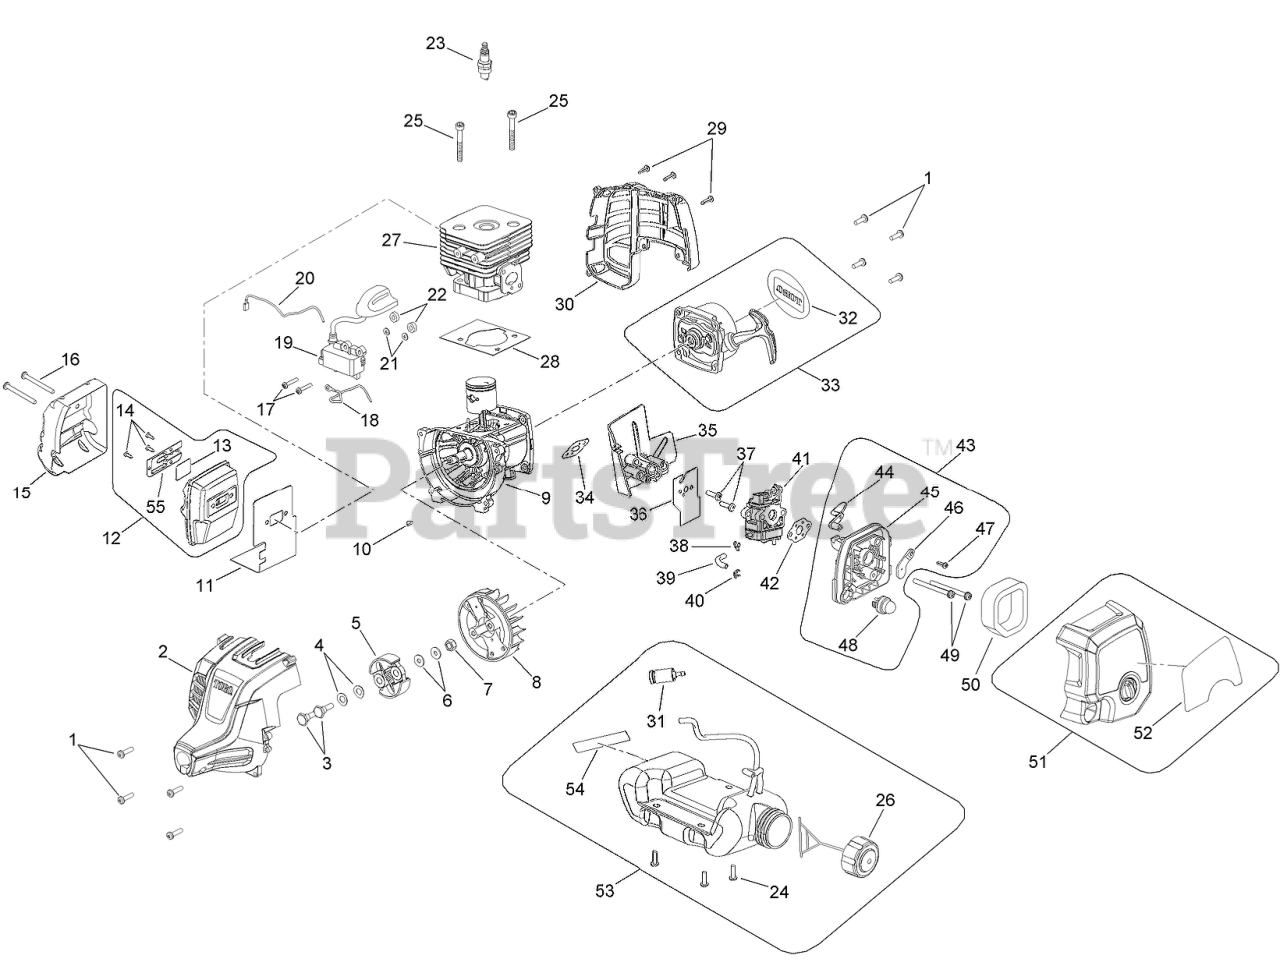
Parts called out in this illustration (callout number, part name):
1	SCREW-PH
2	HOUSING-ENGINE, FRONT
3	SCREW-CLUTCH
4	WASHER-CURVED
5	CLUTCH ASM
7	NUT-ROTOR
9	CRANKCASE ASM
10	KEY-WOODRUFF
11	GASKET-MUFFLER
12	MUFFLER ASM
14	SCREW-PH
15	SHIELD-HEAT
16	SCREW-PH
17	SCREW AND WASHER
18	WIRE-LEAD, RED
19	COIL BOOT ASM
20	WIRE-LEAD, BLACK
23	SPARK PLUG
24	T25 TORX PAN HEAD
25	SCREW-SOCKET HEAD
26	CAP-FUEL
27	CYLINDER
30	HOUSING-ENGINE, REAR
31	FILTER-FUEL
32	PLATE-LOGO
33	RECOIL STARTER AND STARTER CUP ASM
34	GASKET-HEAT DAM
35	HEAT DAM
38	CLIP-HOSE
39	FUEL LINE 45MM
40	CLIP-HOSE
41	CARBURETOR ASM
42	GASKET-CARBURETOR
43	FILTER HOUSING ASM
44	LEVER-CHOKE
45	PLATE-CARBURETOR
46	PLATE-CHOKE
47	SCREW-PH
48	PRIMER ASM
49	T20 TORX CAP SOC HD
50	ELEMENT-FILTER, AIR
51	COVER ASM
52	DECAL-START
53	FUEL TANK AND CAP ASM
54	LABEL-COMBUSTION
55	COVER-TRIMMER
